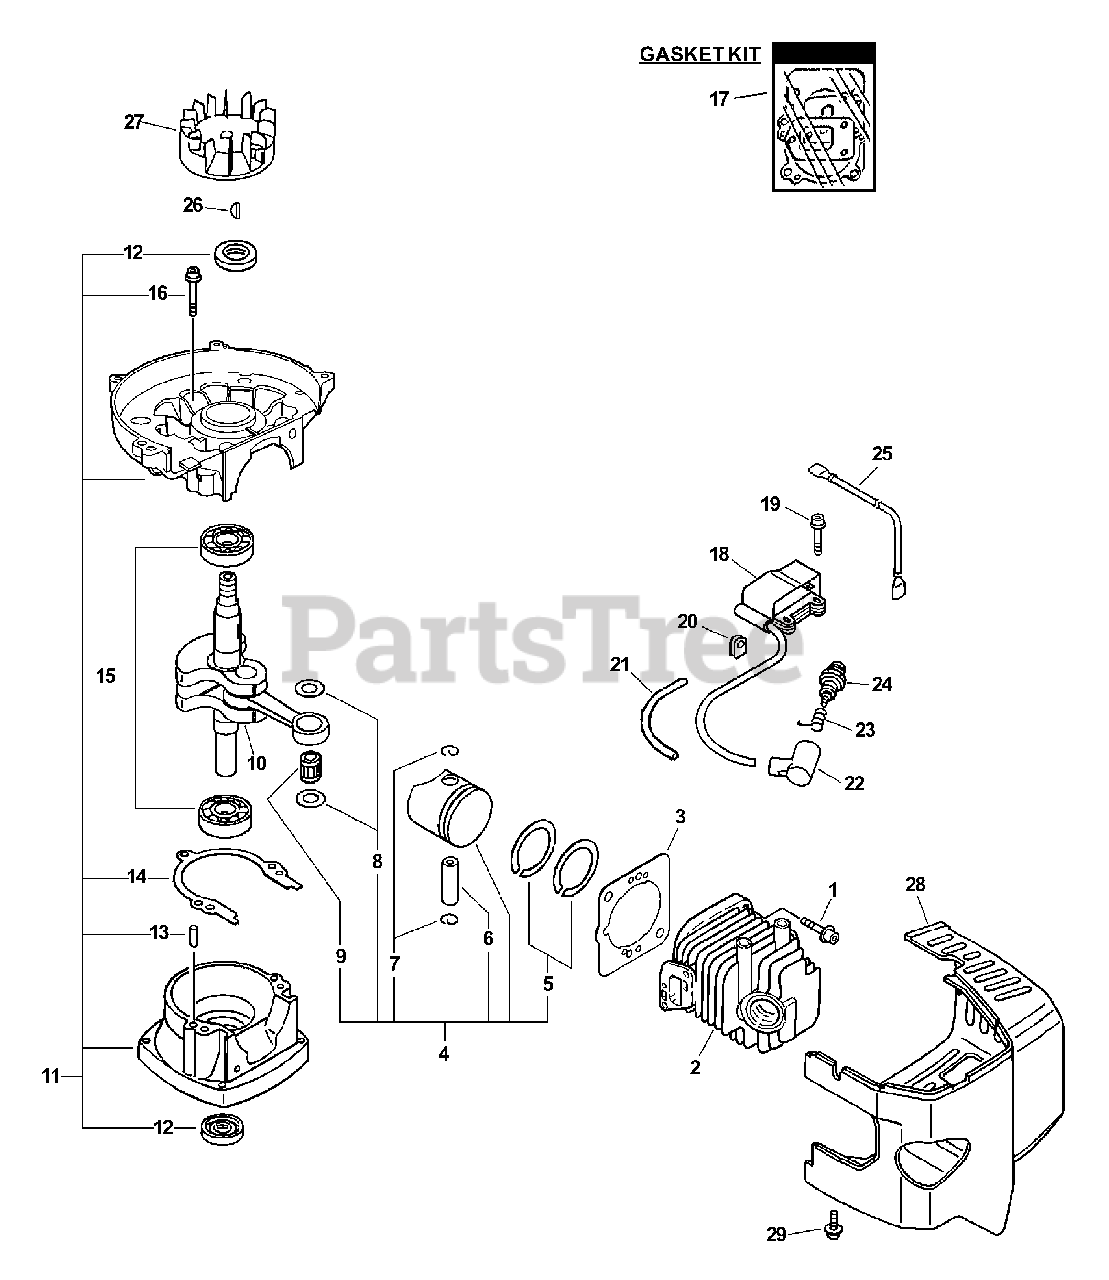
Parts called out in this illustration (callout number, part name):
1	SCREW - 5X22
2	CYLINDER
3	GASKET, CYLINDER
4	PISTON KIT
5	RING, PISTON
6	PIN, PISTON
7	RING, RETAINING
8	SPACER, PISTON
9	BEARING, NEEDLE - 8
10	CRANKSHAFT ASSY
11	CRANKCASE KIT
12	SEAL, OIL
13	PIN - LOCATING
14	GASKET, CRANKCASE
15	BEARING, BALL - 6201
16	SCREW - 5X28
17	GASKET KIT
18	COIL, IGNITION
19	SCREW - 4X20
21	TUBE, INSULATOR
22	CAP, SPARK PLUG
23	TERMINAL, SPARK PLUG CAP
24	SPARK PLUG -- BPM-8Y
25	LEAD - IGNITION
27	FLYWHEEL
28	COVER, ENGINE
29	SCREW - 4X18
